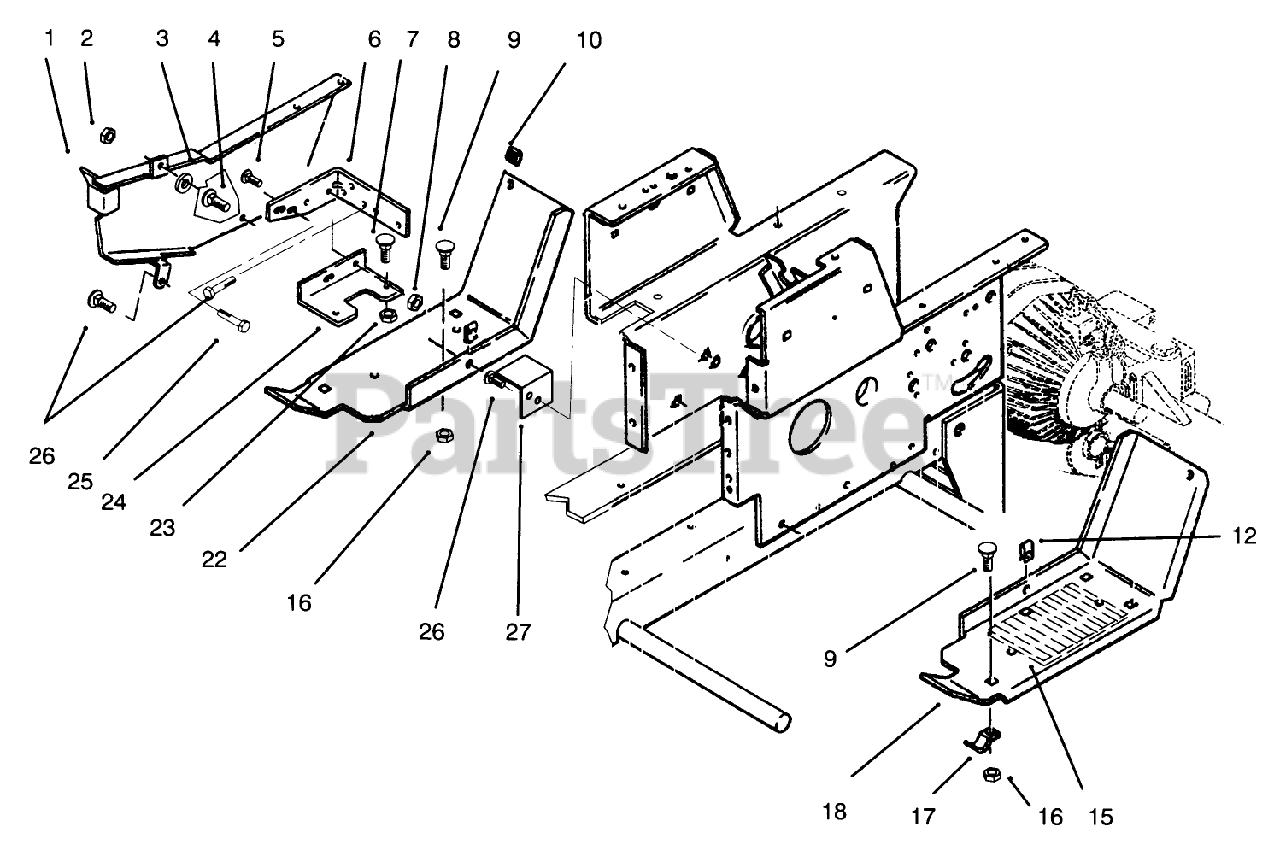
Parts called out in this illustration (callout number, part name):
2	NUT-LOCK, NI
5	SCREW-HH
6	BRACKET-BELT*B
8	NUT-LOCK, NI
9	BOLT-CARR
10	BUMPER
15	PAD FOOTREST
16	NUT-LOCK, NI
17	BRACKET
18	FOOTREST LH *R
24	BRKT-FUS HLDER*B
25	BOLT-CARR
26	SCREW
27	BRCKET-BLT SUT*B
